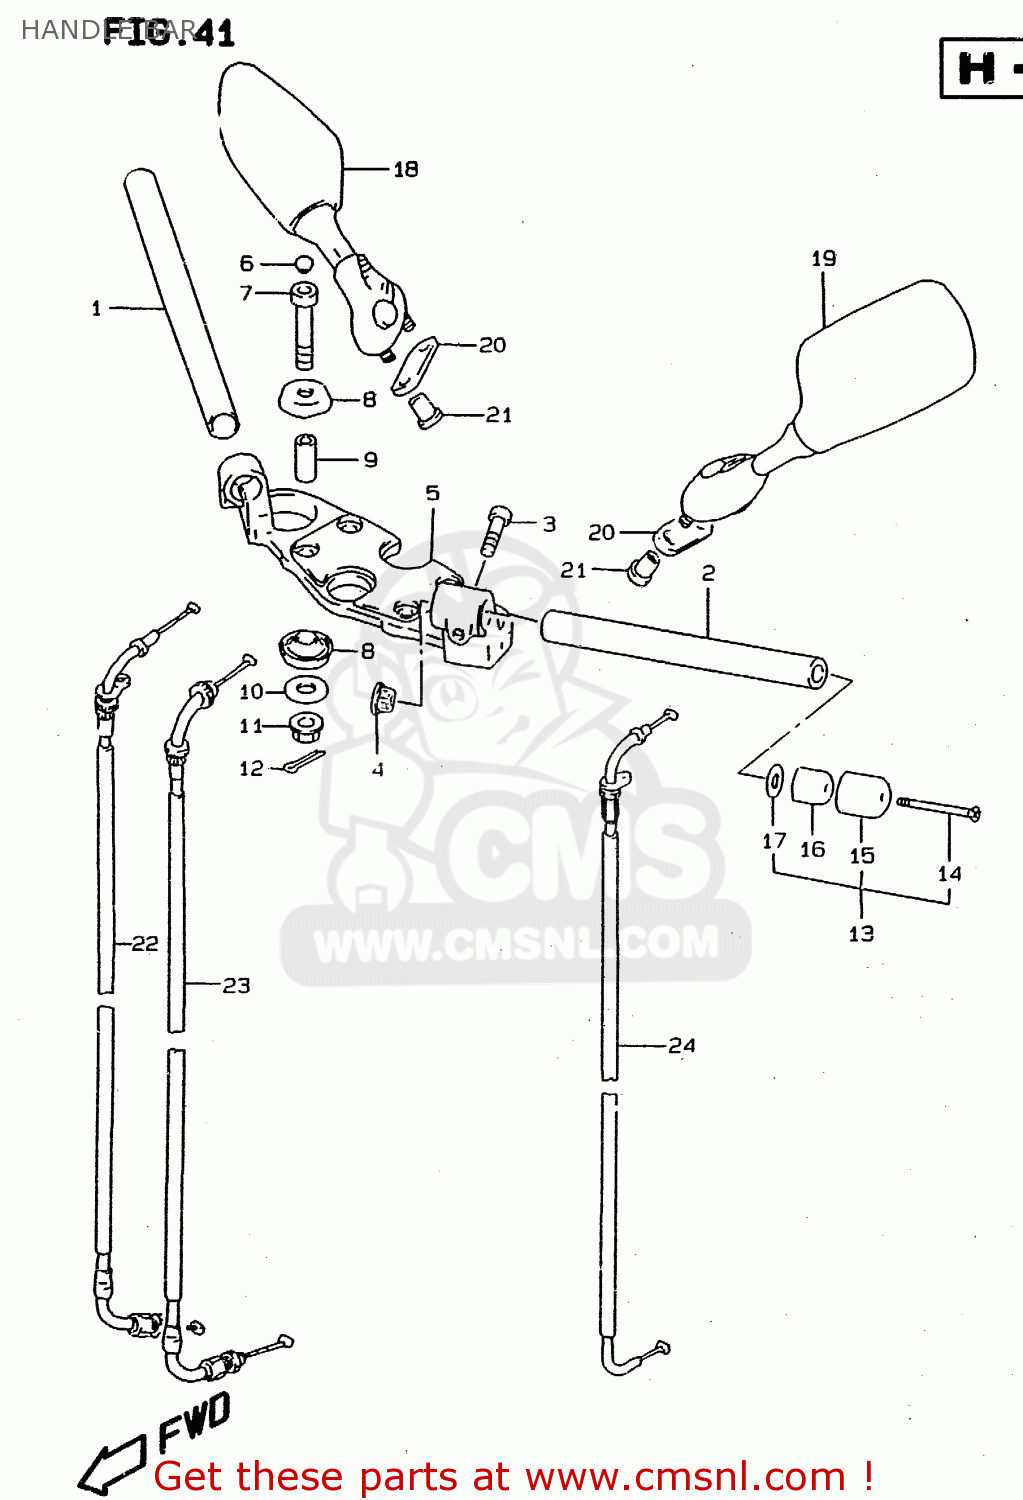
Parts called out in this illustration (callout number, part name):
1	HANDLEBAR
2	HANDLEBAR,L
3	BOLT
4	CAP,HANDLEBAR
5	HOLDER,HANDLEBAR
6	CAP(OD:11)
7	BOLT(10X66)
8	CUSHION,UPR BRACKET
9	SPACER,STEERING STEM HEAD
10	WASHER(10.5X30X3.2)
11	NUT
12	PIN 20X20
13	BALANCER SET,HANDLEBAR
14	SCREW
15	CAP,BALANCER
16	BALANCER,HANDLEBAR
17	SPACER,BALANCER
18	MIRROR ASSY,RR VIEW,R
19	MIRROR ASSY,RR VIEW,L
20	CUSHION,RR VIEW MIRRORR
21	NUT,RR VIEW MIRROR
22	CABLE ASSY,THROTTLE NO.1
23	CABLE ASSY,THROTTLE NO.2
24	CABLE COMP,STARTER
